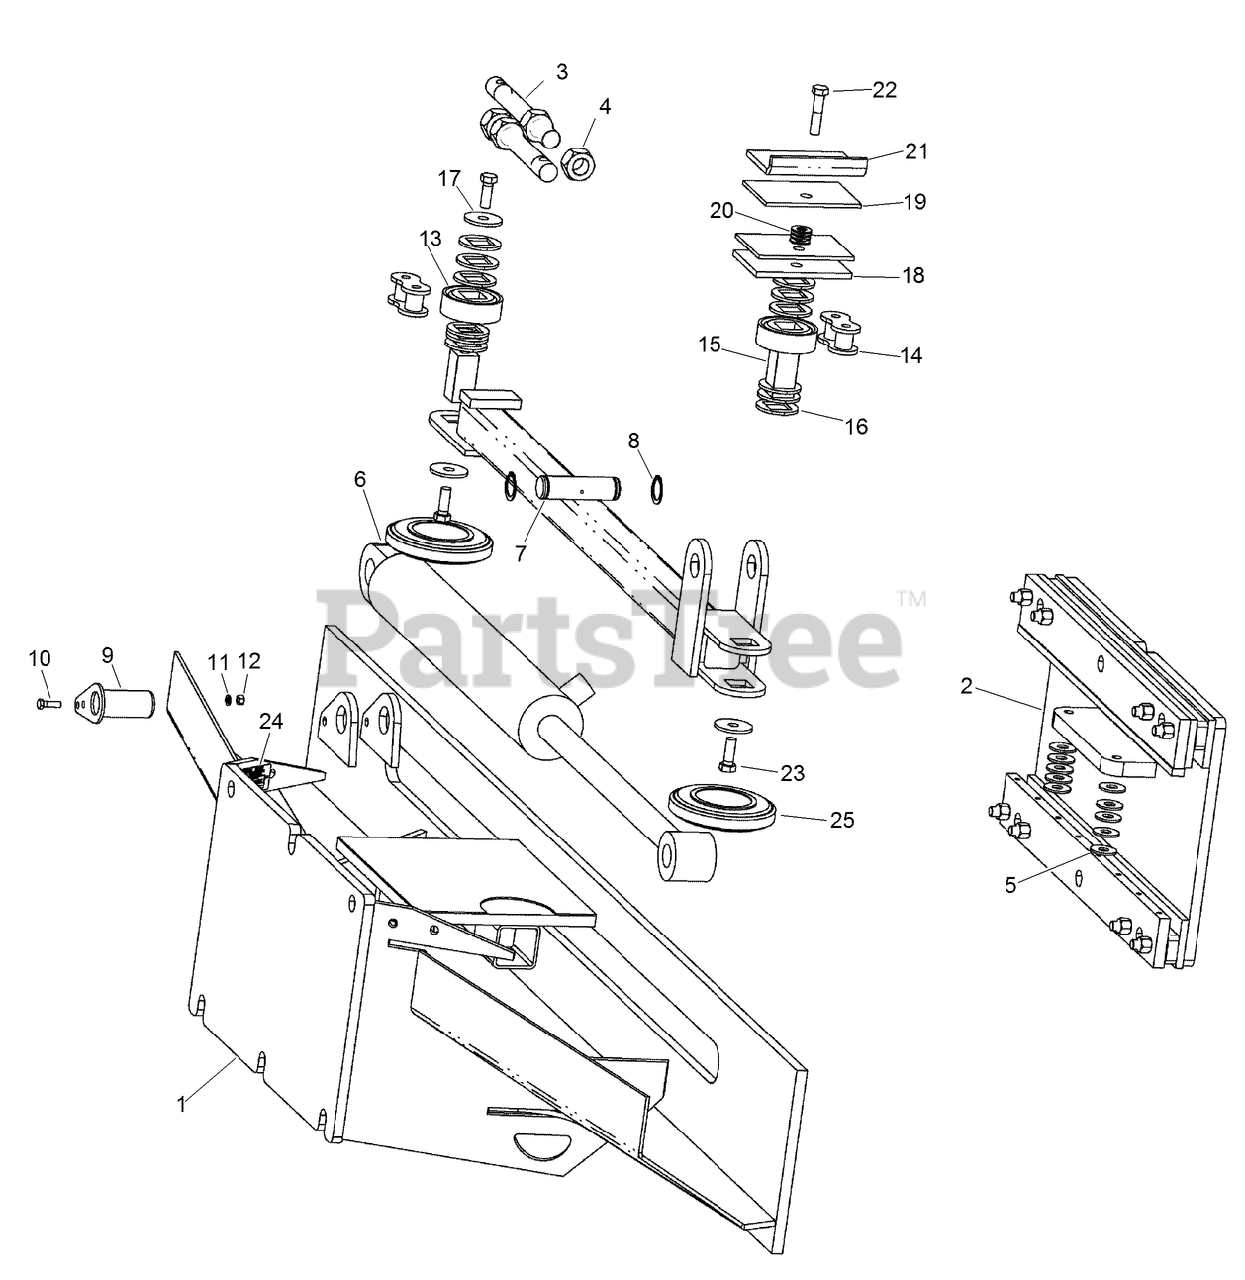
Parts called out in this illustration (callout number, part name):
1	Weldment, Offset Slider
2	SLIDE MOUNT ASM
3	NUT-HEX
4	ROD-THREADED
5	WASHER-FLAT
6	CYLINDER - Boom
7	PIN-PIVOT
9	PIN-BOOM (CYLINDER)
10	BOLT
11	WASHER-Spring Lock, Reg 3/8 ZND
12	NUT-HEX
13	BEARING
14	CHAIN ASM
15	BAR-AXLE, ROLLER
16	WASHER
18	Plate, Slide
19	SHEET-WEAR STRIP
20	WASHER-FLAT
21	Plate, Slide, Upper
22	BOLT-hex, 5/8 NC x 2-3/4 inch, grade 8
23	SCREW-HH
24	PLATE - Serial Number
25	WHEEL-BOOM END, IDLER
